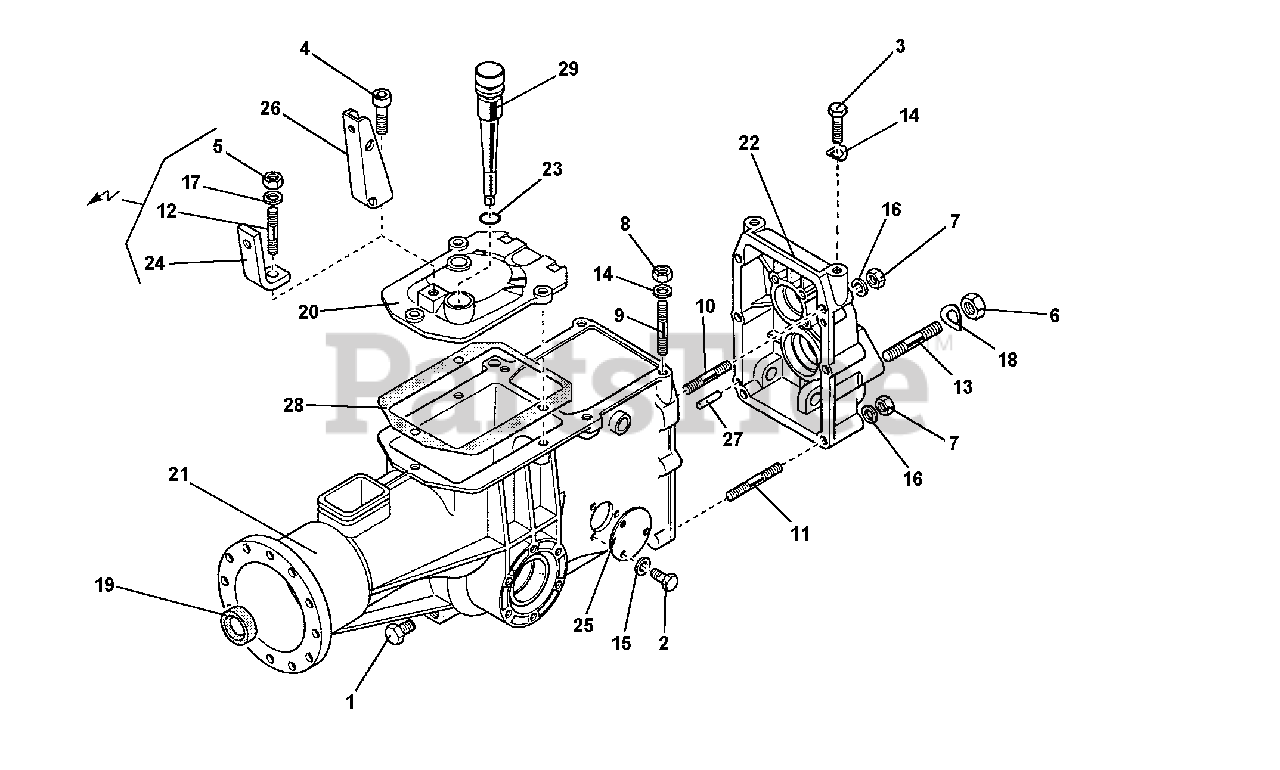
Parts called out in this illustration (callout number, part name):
2	SCREW M6X10
3	SCREW M8X20
4	SCREW M10X25
6	NUT, M12X1.25
7	NUT, SELF LOCKING M8
9	SUTD M8X38X14X20
10	STUD, M8X58X16X16
11	STUD, M8X68X16X16
12	STUD, M10X37X19X15
13	STUD, M12X1.25X12X52
14	SUPER WASHER
15	WASHER, LOCK 6.4
16	WASHER, LOCK 8.4
17	WASHER, LOCK 10.4
18	WASHER, LOCK 13.4
24	CLUTCH BRACKET
26	CLUTCH BRACKET
27	PARALLEL PIN
28	GASKET, COVER
